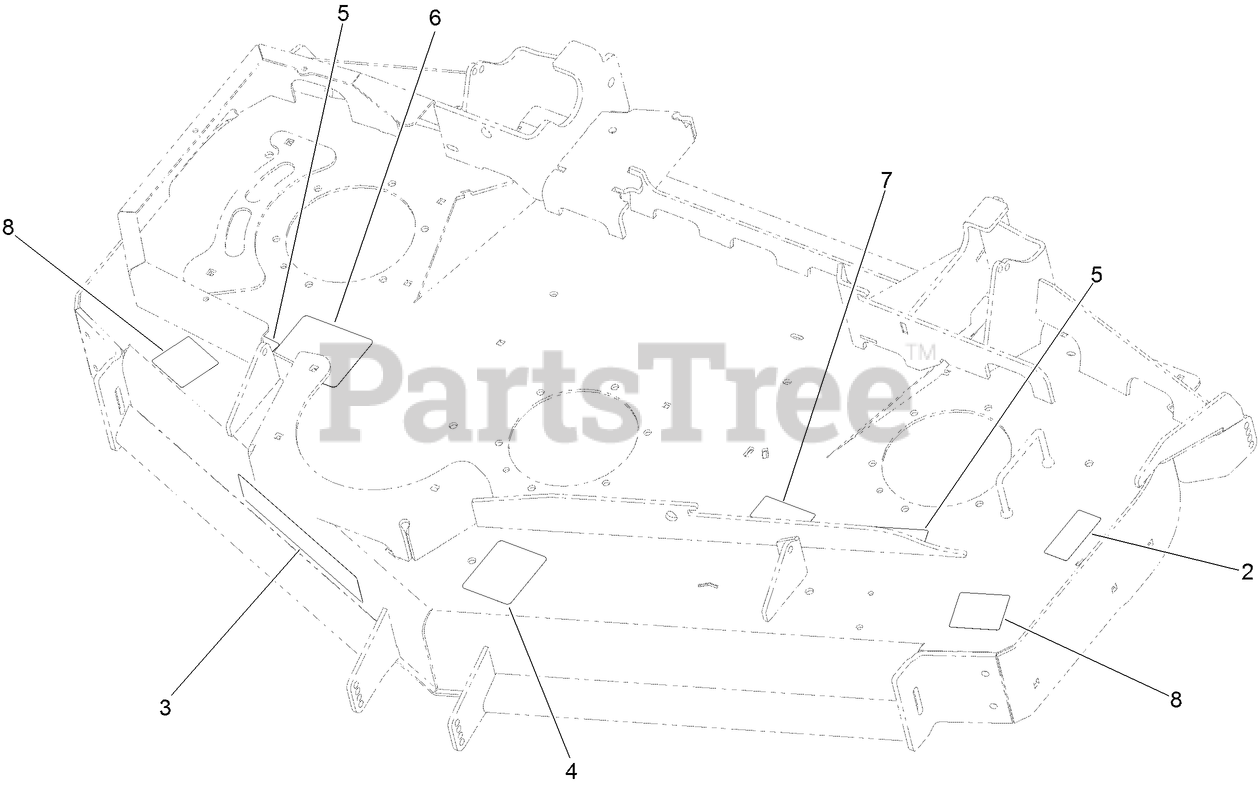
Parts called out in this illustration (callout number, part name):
2	DECAL-BOLT TORQUE
4	DECAL-ROLLER, ANTI-SCALP
5	DECAL-COVER, MISSING
6	DECAL-SPINDLE CR, CE
7	DECAL-BELT ROUTING REAR
8	DECAL-DANGER, THROWN OBJECT
